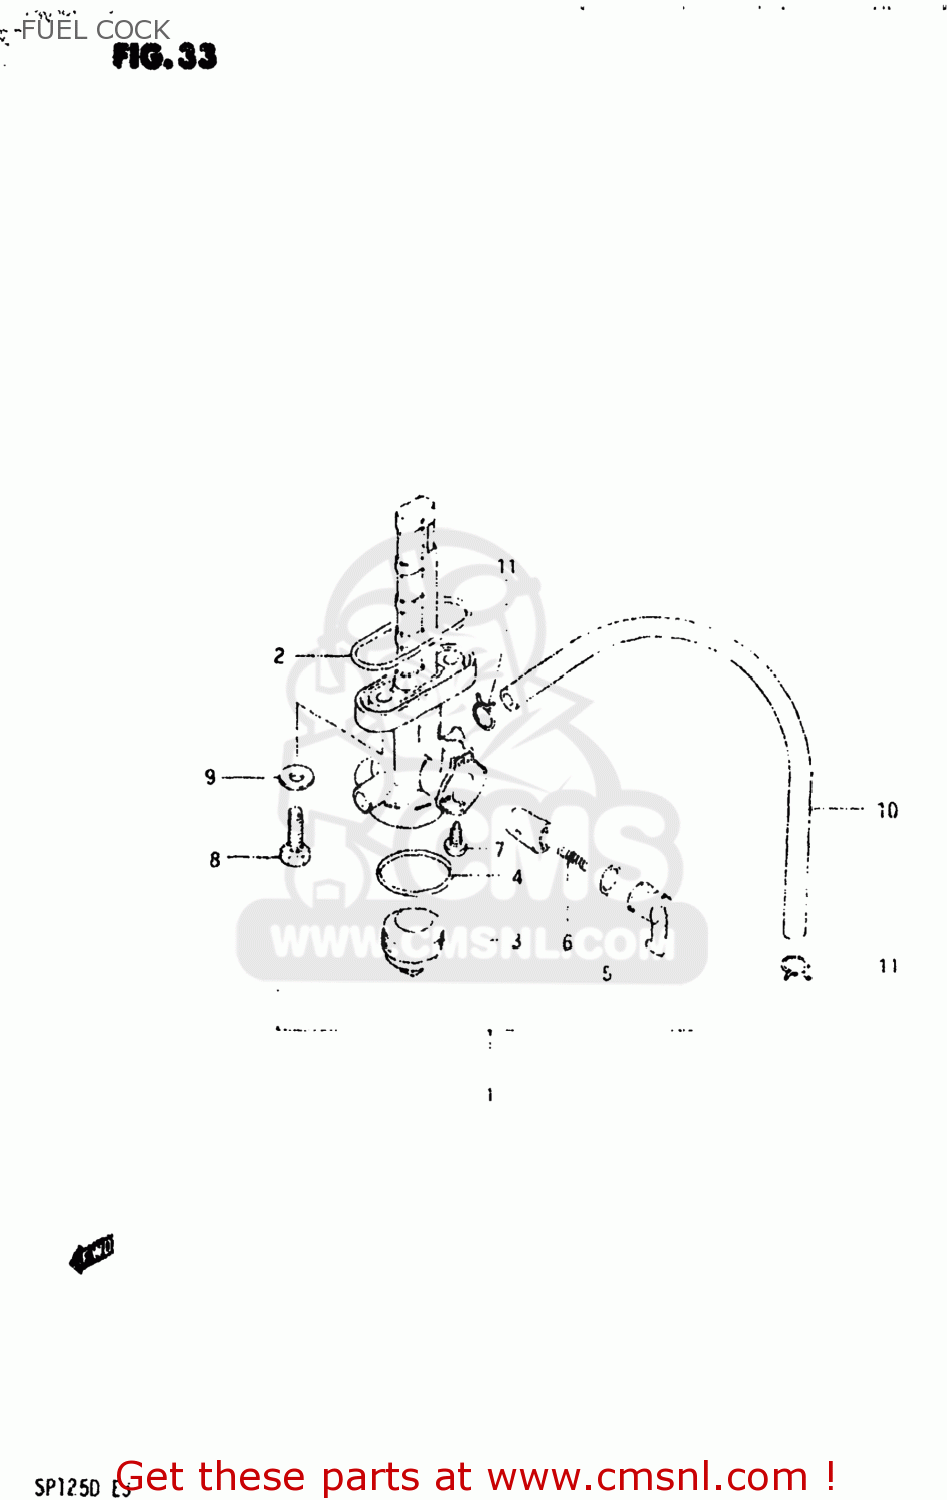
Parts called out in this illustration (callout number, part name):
1	COCK ASSEMBLY,FUEL
2	O RING,FUEL COCK
3	CUP,STRAINER
4	GASKET,FILTER (NAS)
5	O-RING
6	SPRING
7	SCREW
8	BOLT(6X20)
9	GASKET
10	HOSE
11	CLIP
